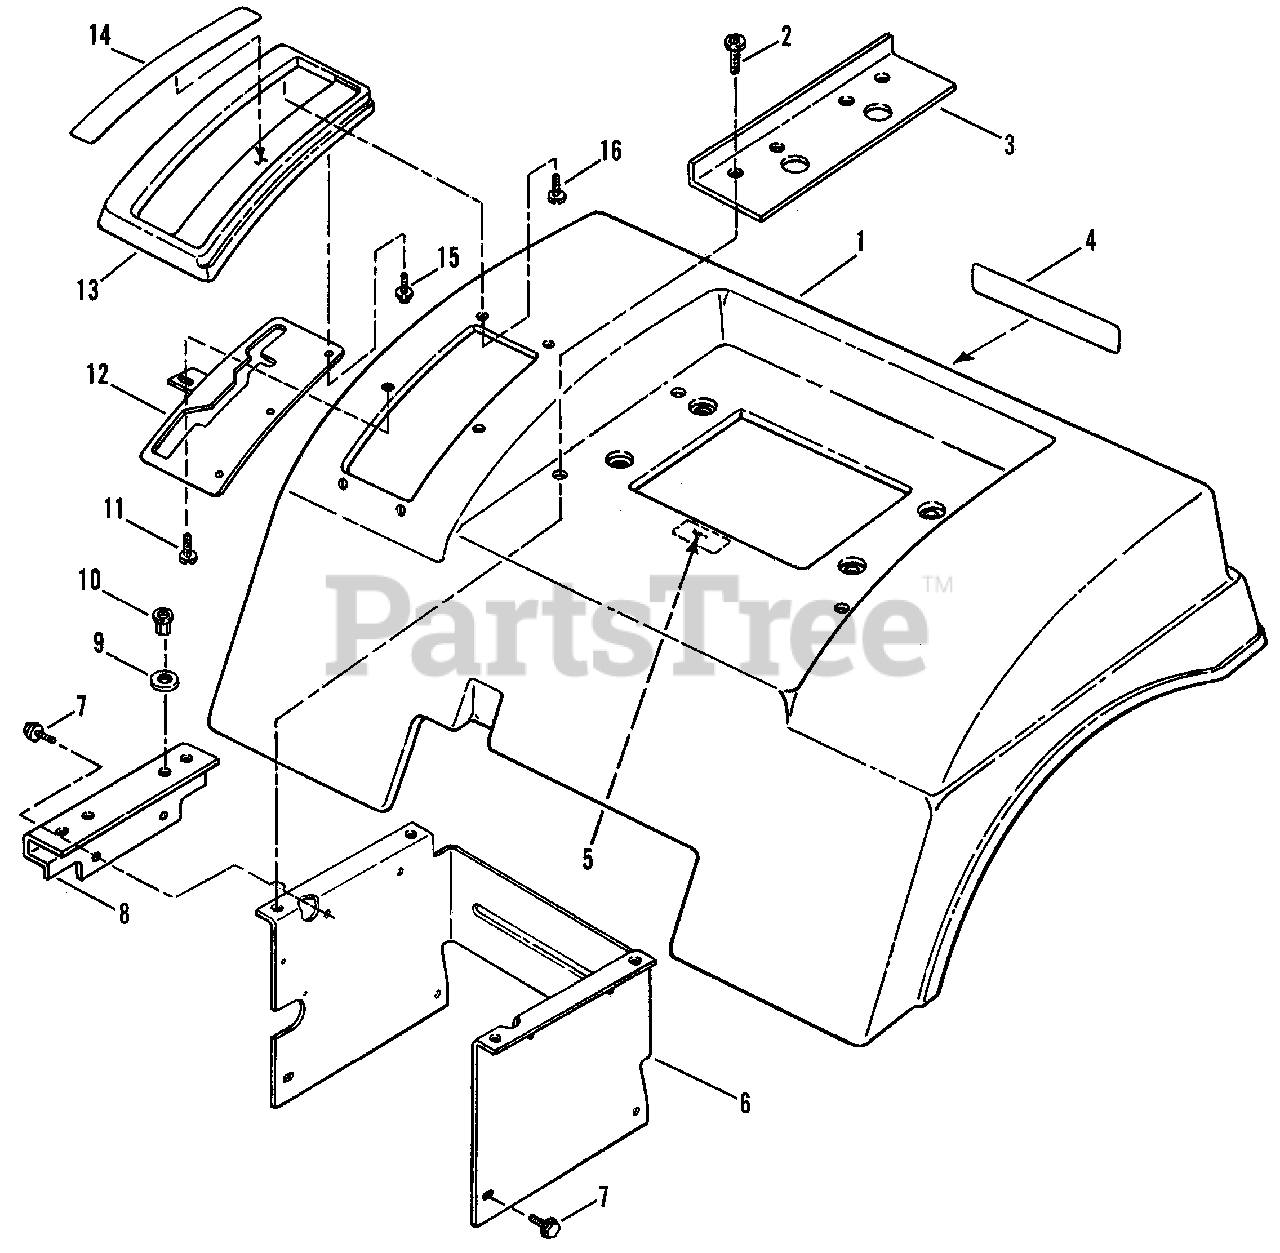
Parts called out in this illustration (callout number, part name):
1	PAN, Seat (Fender)
2	SCREW, 5/16-18 x 5/8" Truss Head (Torx
3	BRACE, Fender
4	DECAL - BLACKHAWK, Molded Logo
5	DECAL - CAUTION, Battery Installation
6	SUPPORT, Fender
7	SCREW, 5/16-18 x 5/8" Hex Washer Head, Self-Tapping
8	BRACKET, Fender Support
9	WASHER, Flat
10	RIV-NUT, 5/16-18
11	SCREW, #10-16 x 3/4" Pan Head, Self-Tapping
12	DETENT, Gear Shift
13	COVER, Shift
14	DECAL, Shift Cover, 6-Speed
15	SCREW, #10-16 x 1/2" Hex Washer Head, Self-Tapping
16	SCREW, #10-16 x 5/8" Pan Head, Self-Tapping
